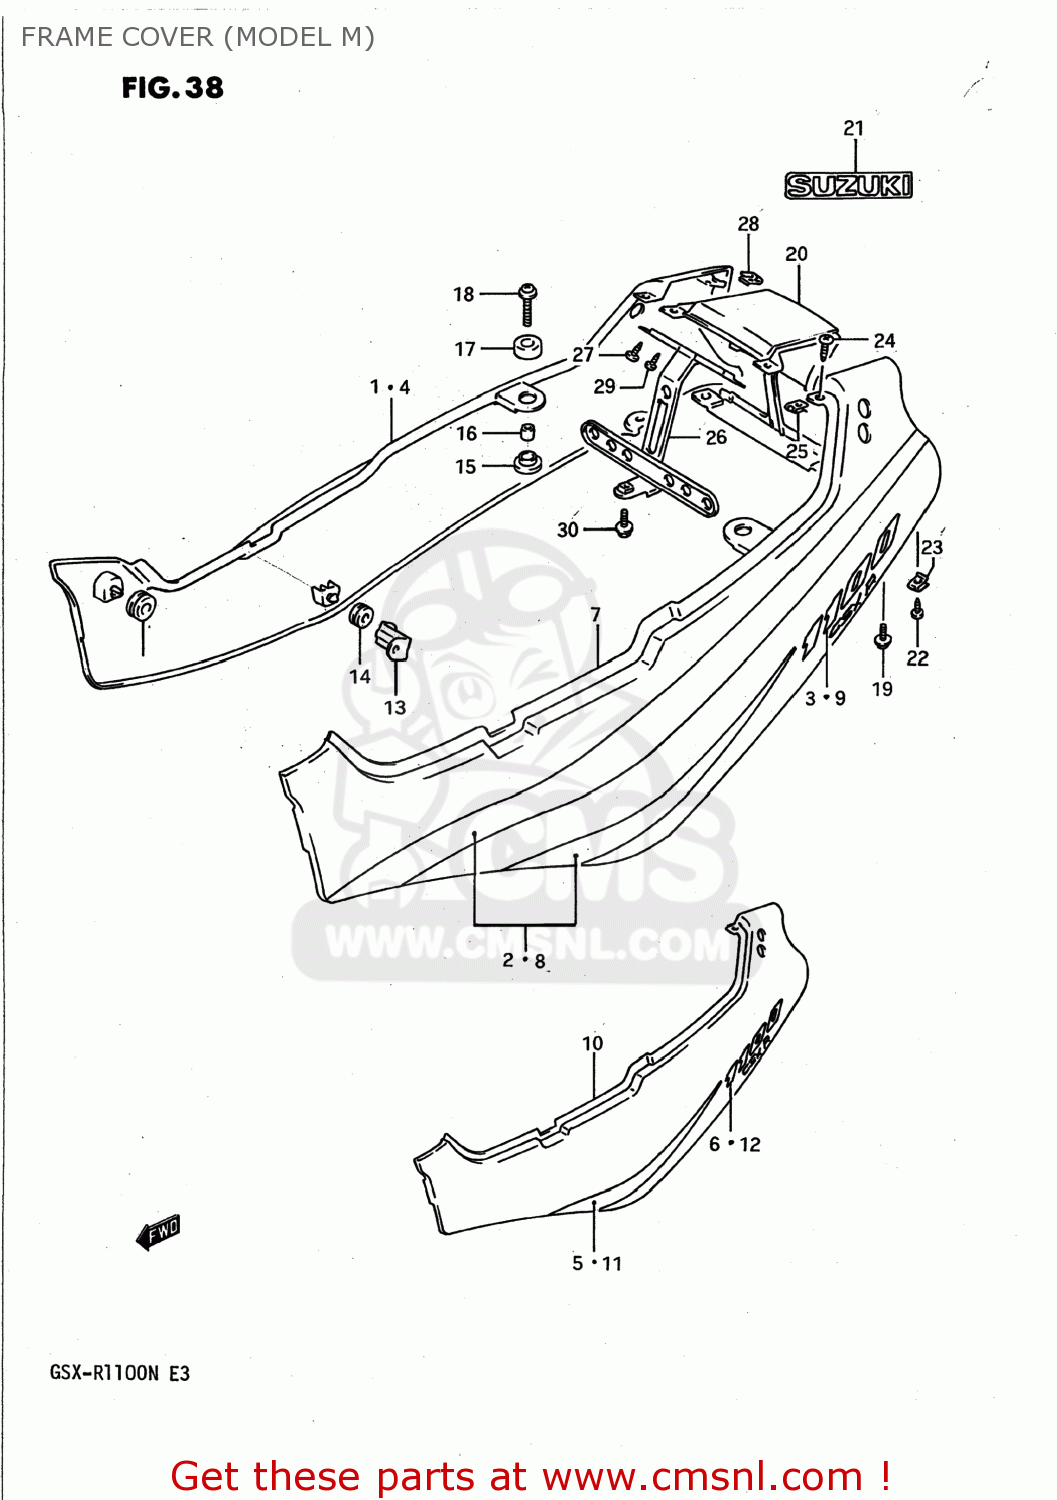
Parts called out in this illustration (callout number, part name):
1	COVER COMP,FRAME,RIGHT
2	TAPE SET,FRAME COVER
3	EMBLEM,FRAME COVER
4	COVER,FRAME,R
5	TAPE,FRAME COVER
6	EMBLEM,FRAME COVER
7	COVER,FRAME,L
8	TAPE SET,FRAME COVER
9	EMBLEM,FRAME COVER
10	COVER COMP,FRAME,LEFT
11	TAPE,FRAME COVER
12	EMBLEM,FRAME COVER
13	BRACKET,FRAME COVER
14	CUSHION
15	CUSHION,FRAME COVER LWR
16	SPACER
17	CUSHION,TAIL COVER UPR
18	SCREW(6X30)
19	SCREW (6X16)
20	COVER,FRAME CTR
21	EMBLEM
22	SCREW
23	NUT
24	SCREW, BRACKET
25	NUT
26	BRACKET,TAIL LAMP
27	SCREW, BRACKET
28	NUT
29	SCREW
30	BOLT
